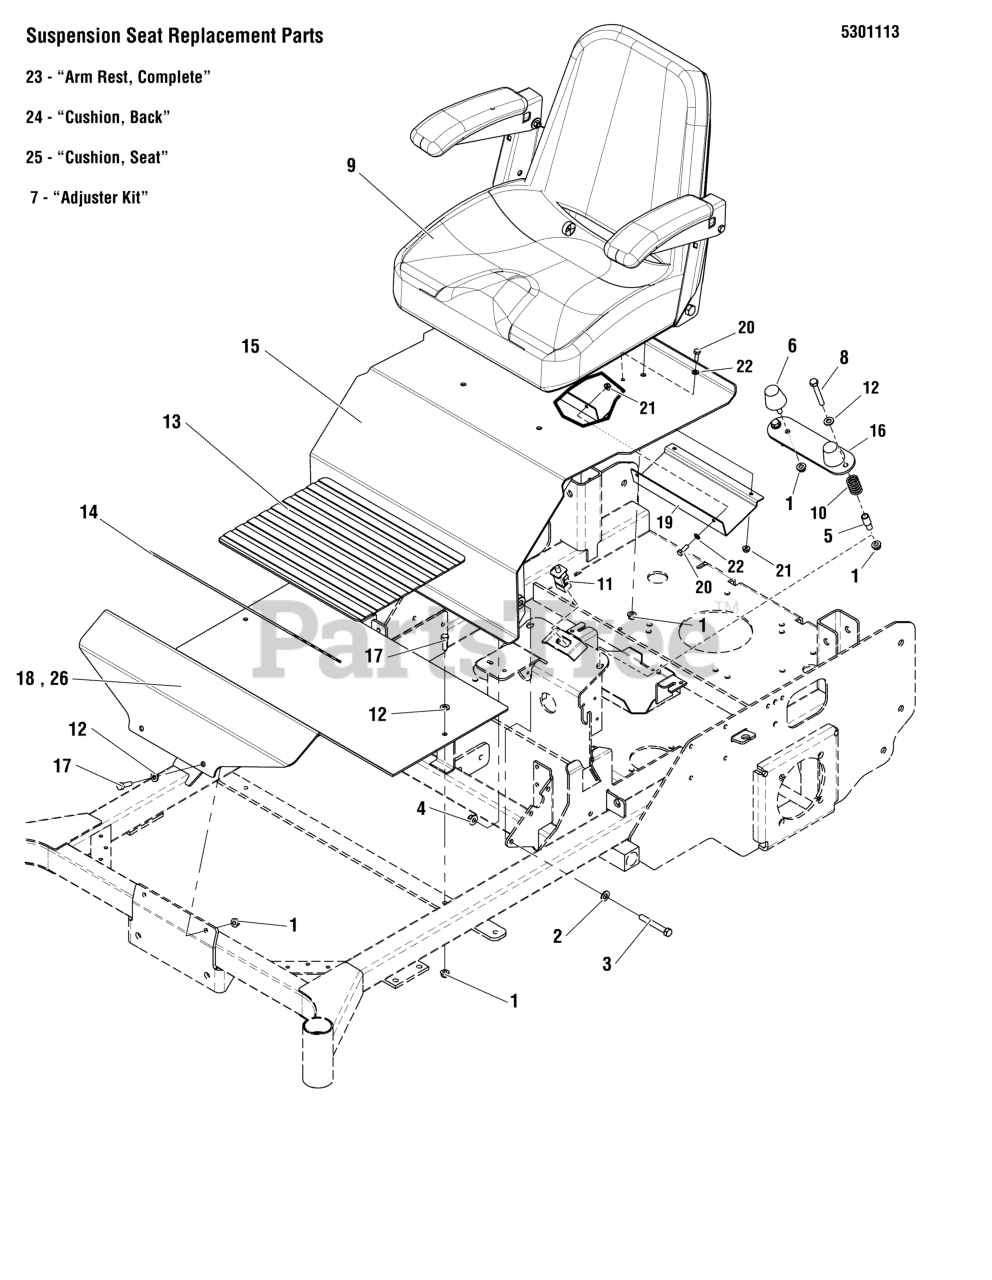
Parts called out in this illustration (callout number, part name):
1	NUT, 5/16-18 HEX NYLOCK FLANGE
2	WASHER, 3/8 SAE
3	BOLT, 3/8-16 X 2, GD5, CZ
4	NUT, 3/8-16 HEX NYLOCK FLANGE
5	SPACER, .328 ID X .66, YZ
6	BUMPER, RUBBER 5/16-18
7	KIT, ADJUSTER, S/S (SV)
8	BOLT, 5/16-18 X 2-1/4" GD5 YZ
9	SEAT, SUSP. TYPE, MICHIGAN SEAT, V5300, BLK
10	SPRING, COMP 720ID X 1.310LG X .118WIRE
11	SWITCH, PLUNGER, NO/NO SNAP IN
12	WASHER, 5/16" SAE
13	SAFETY WALK, 11.50 X 19.00
14	SAFETY WALK, 10.00 X 19.00
15	ASSM, SEAT PLATE W/ DECALS - S200X
16	PLATE, SEAT SWITCH - RED
17	BOLT, 5/16-18 X 1 GD5 YZ
18	PLATE, FLOOR PAN, SNP RED
19	PLATE, SEAT SUPPORT EXTENSION
20	BOLT, 1/4-20 X 3/4 GD5 YZ
21	NUT, 1/4-20 HEX NYLOCK FLANGE
22	WASHER, 1/4 SAE
23	KIT, ARM REST, S/S (SV)
24	CUSHION, BACK, S/S (SV)
25	CUSHION, SEAT, S/S (SV)
26	PLATE, FLOOR PAN, S200X - SNAPPER RED
